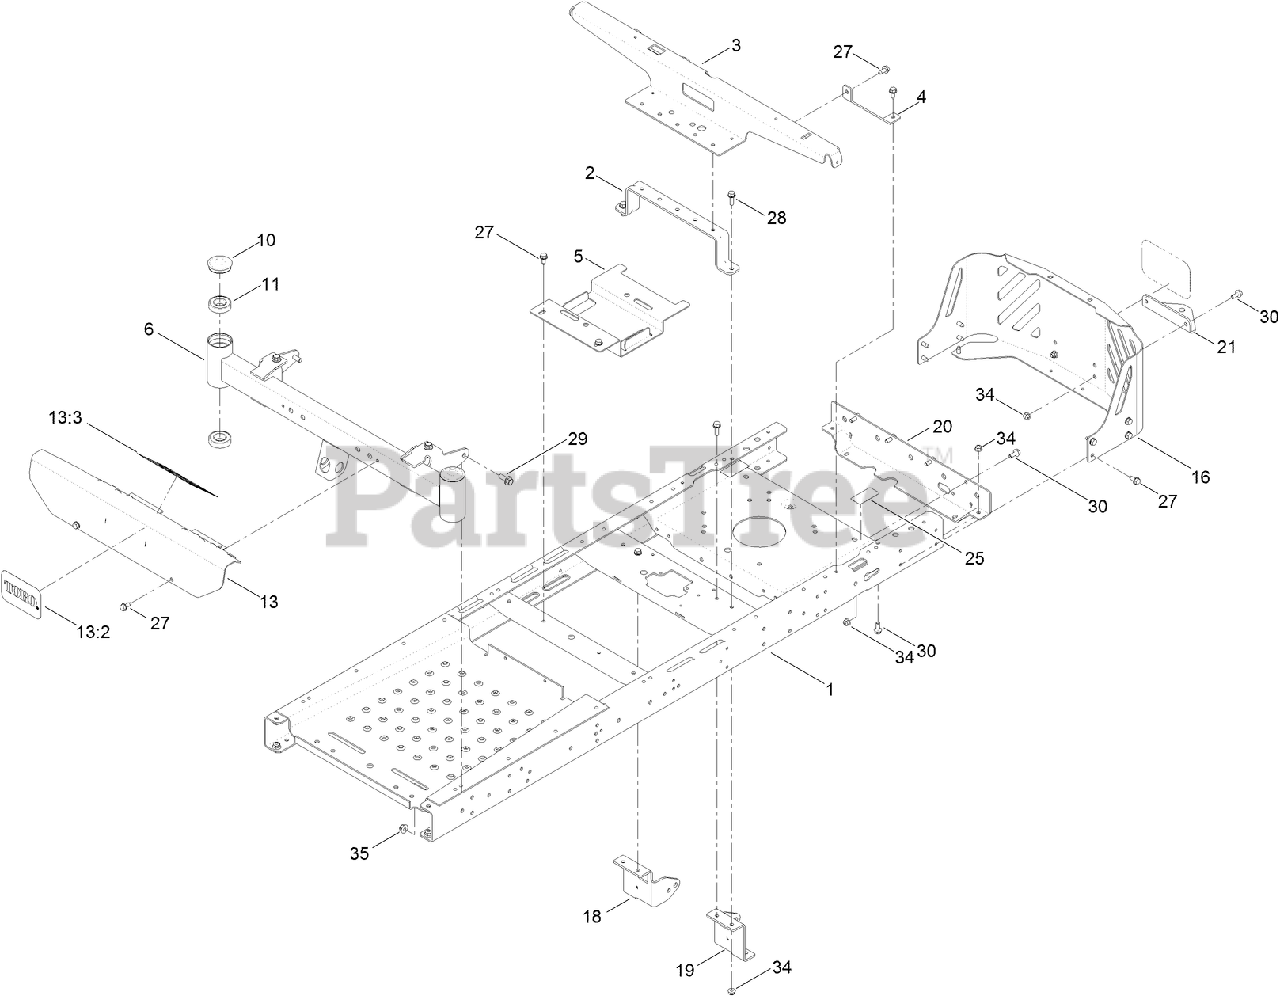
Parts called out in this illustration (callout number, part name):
1	FRAME ASM
2	BRACE-SEAT, REAR (NARROW)
3	SUPPORT-POD
4	SUPPORT-TANK, REAR
5	BRACKET-BATTERY
6	AXLE-FRONT, NARROW
10	CAP-GREASE
11	BEARING-BALL
13	FOOTREST ASM
13:3	DECAL-DANGER
16	GUARD-ENGINE, NARROW
18	MOUNT-HYDRO, FRONT (RH)
19	MOUNT-HYDRO, FRONT (LH)
20	CROSSMEMBER-REAR, NARROW
21	BRACKET-HITCH
25	DECAL-BYPASS
27	SCREW-HWHTF
28	SCREW-HHF
29	SCREW-HHF
30	SCREW-HHF
34	NUT-HF, NI
35	NUT-HF, NI
